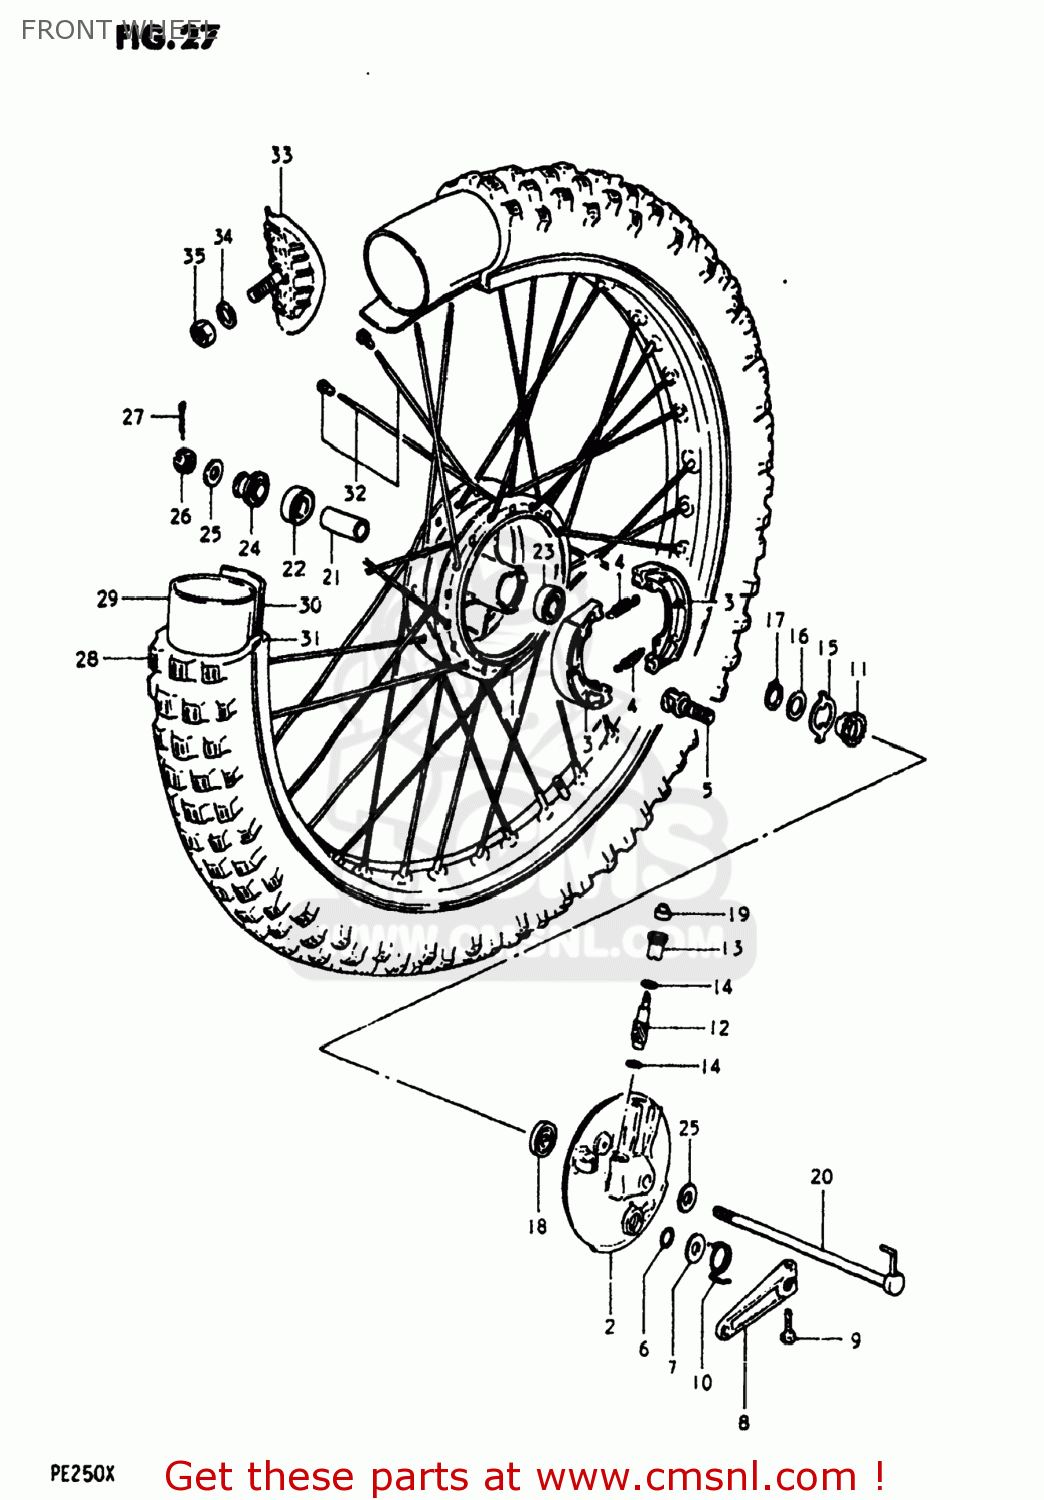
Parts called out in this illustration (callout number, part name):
1	DRUM,FRONT HUB
2	PANEL,FRONT HUB
3	SHOE,BRAKE
4	SPRING
5	CAM,FRONT BRAKE
6	O-RING,BOSS
7	WASHER (15X24X1.6)
8	LEVER,FRONT BRAKE CAM
9	BOLT
10	SPRING
11	GEAR,SPEEDOMETER
12	PINION,SPEEDOMETER
13	BUSHING,SPEEDOMETER PINION
14	WASHER (5.1X9X0.4)
15	DRIVER,SPEEDOMETER GEAR
16	WASHER(22.5X27X1)
17	CIRCLIP
18	SEAL,OIL(26X38X4)
19	SEAL,OIL(6X10X3)
20	AXLE,FRONT
21	SPACER (12.6X19X52)
22	BEARING, RH
23	BEARING
24	SPACER,FRONT AXLE,RIGHT
25	WASHER
26	NUT, REAR AXLE
27	COTTER PIN
28	TIRE,FRONT
29	TUBE,INNER
30	PROTECTOR,WHEEL,INNER
31	RIM,FRONT WHEEL
32	SPOKE SET,FRONT
33	STOPPER,BEAD
34	WASHER
35	NUT
